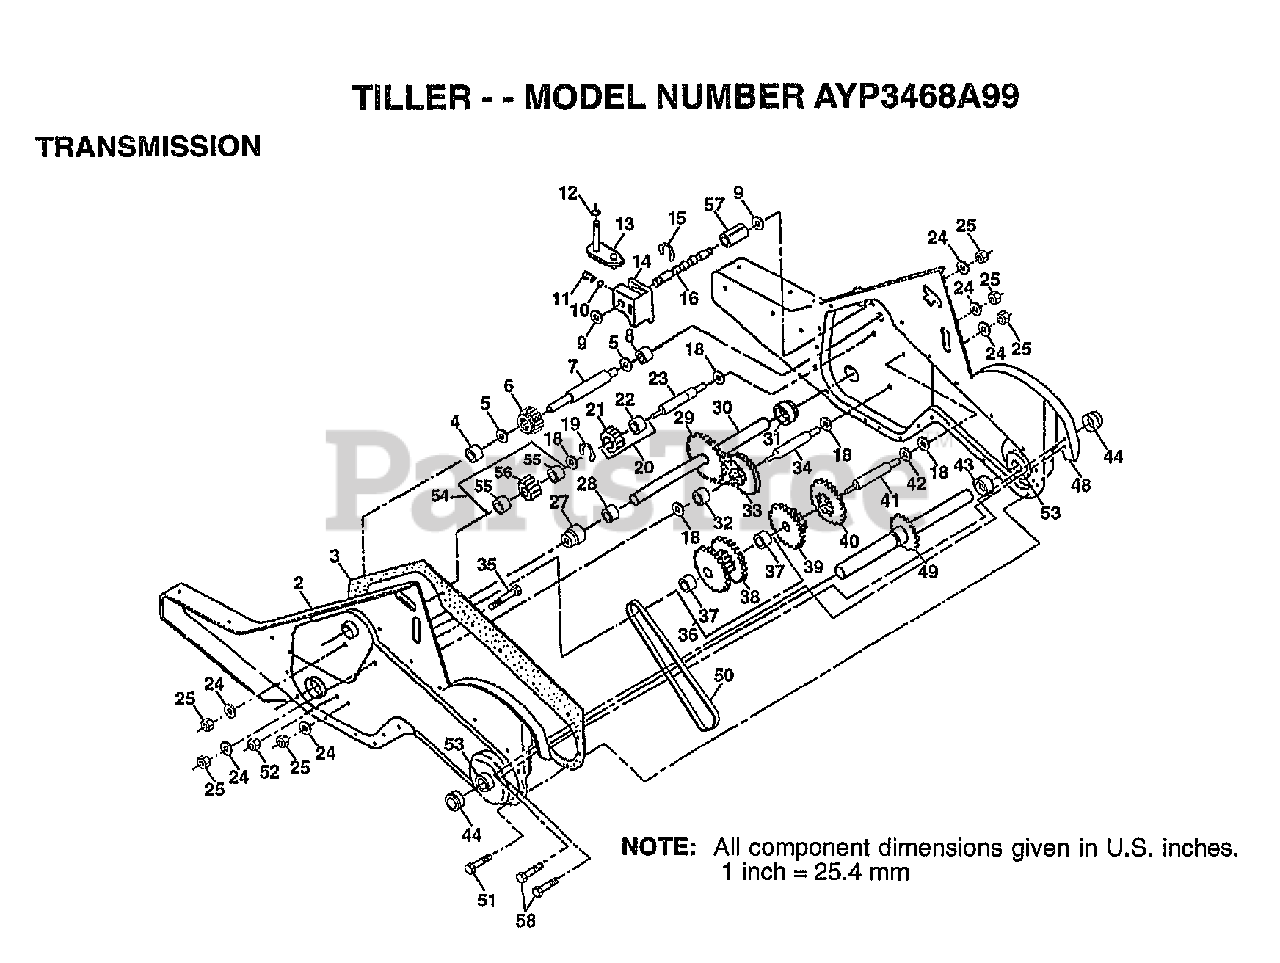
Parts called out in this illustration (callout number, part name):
1	TRANSMISSION ASSM.
2	GEARCASE.ASM.LH.W/BEARING
3	GASKET.GEARCASE
4	NEEDLE BRNG LT
5	"T, BEARING"
6	PINION
7	SHAFT
8	"TI, BEARING"
9	WASHER SEAL
11	SPRING-SHIFT CRT
12	O-RING TI
13	BRACKET ASM SHIFT
14	SHIFT FORK TI
15	KLIP RING
16	SHAFT
18	WASHER
19	KLIP RING
20	GEAR ASSY CRT
21	GEAR-REV IDLR CRT
22	NEEDLE BEARING TI
23	SHAFT.IDLER.REVERSE.CRT
24	LOCKWASHER
25	NUT.ASF.HEX.7/16
27	BEARING.SHAFT.LH.
28	BUSHING TI
29	CHAIN CRT
30	GROUND SHAFT ASSY
31	BEARING.SHAFT.RH.
32	SPACER TI
33	SPRCKT 8 GEAR CRT
34	SHFT 2ND RED. CRT
35	SCRW WHIZ LOK CRT
36	GEAR & SPROCKET.ASM.W?BEARING
38	ASM.GEAR & SPROCKET
39	GEAR.CLUSTER.DRT.
40	GEAR TI
41	SHAFT
42	BRNG RACE
43	SPACER TI
44	SEAL ASM-OIL
48	GEARCASE
49	TINE SHAFT
50	CHAIN.50 LINK TI
51	SCREW
52	NUT.HEX.5/16-18
53	KIT.BEARING
54	GEAR
55	BEARING
56	GEAR
57	SPACER
58	SCREW 1/4-20X3/4
